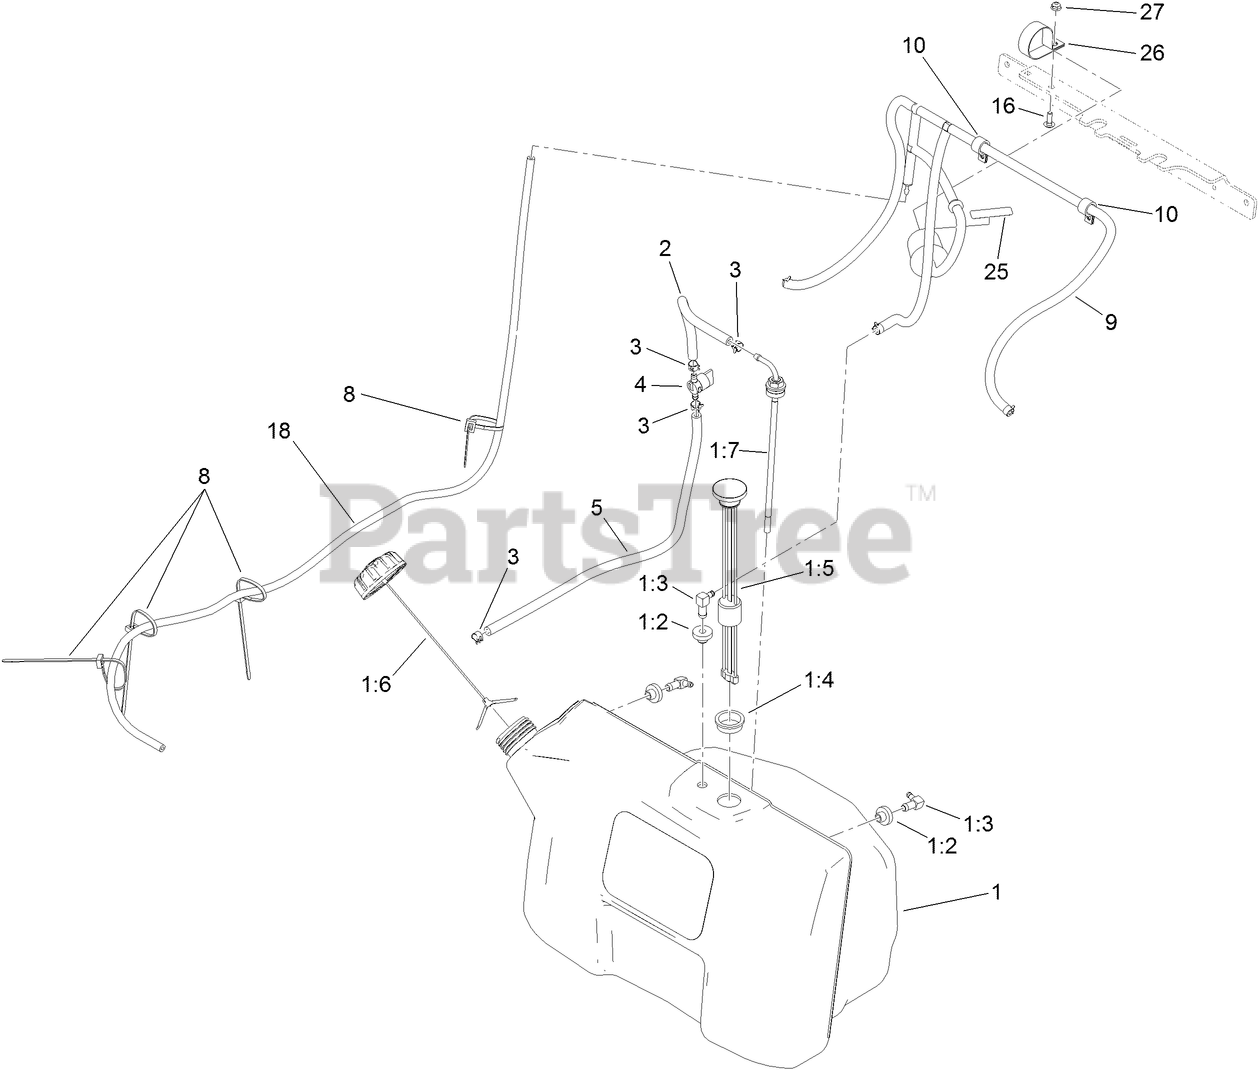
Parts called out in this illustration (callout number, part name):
1	TANK ASM
1:2	BUSHING
1:3	ELBOW-90 DEG
1:4	GROMMET
1:5	GUAGE-FUEL
1:6	CAP-FUEL, RATCHETING
1:7	FITTING-FUEL, BULKHEAD
2	HOSE-FUEL
3	CLAMP-HOSE
4	VALVE-FUEL
5	HOSE-FUEL
8	TIE-CABLE
9	VENT HOSE ASM
10	CLAMP-CABLE
16	BOLT-CARR
18	HOSE-FUEL
25	DECAL-FILTER, EMISSIONS
26	CLAMP-R
27	NUT-HF
